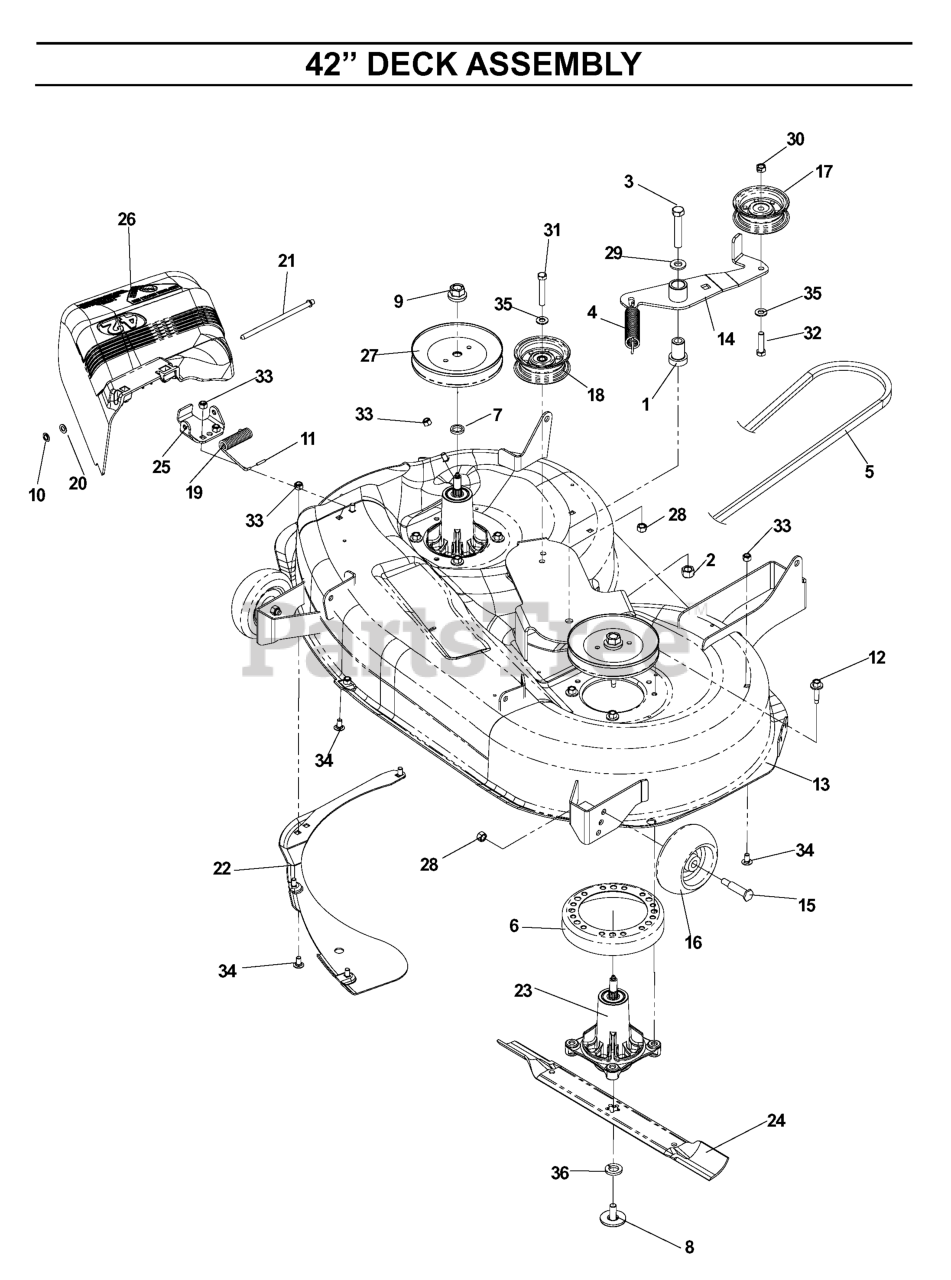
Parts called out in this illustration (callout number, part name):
1	IDLER SPINDLE
2	NUT 1/2-13 HEX NYLOC ZD
3	HCS 1/2C X 2 3/4
5	BELT, MULE DRIVE
6	STRIPPER-ROUND-UNIVERSAL
7	WASHER-SPACER
8	BLADE BOLT ASSY-7/16" TB REPL
9	LOCKNUT - 9/16
10	PUSH NUT
11	CAP-SLEEVE
12	WASHER HEAD SCREW
13	42" PAINTED DECK ASM
14	DECK IDLER ARM WELDMENT
15	BOLT, SHOULDER
16	WHEEL GUAGE
17	PULLEY, IDLER, SHORT
18	IDLER PULLEY ASM
19	SPRING, TORSION DEFLECTOR
20	WASHER, 11/32 X 5/8 X 16 GA
21	ROD, HINGE
22	BAFFLE VORTEX 42
23	MANDREL GREASABLE
24	BLADE 42" MULCHING STD
28	NUT 3/8-16 NYLOC
29	WASHER 1/2" FLAT
30	NUT 3/8C CENTERBLOCK
31	HCS 3/8C X 2 1/4
32	HCS 3/8C X 1 1/2
33	NUT 5/16 NYLOC
34	CARRIAGE BOLT 5/16C X 5/8"
35	WASHER 3/8 SAE FLAT
36	WASHER, 7/16 DISC SPRING
